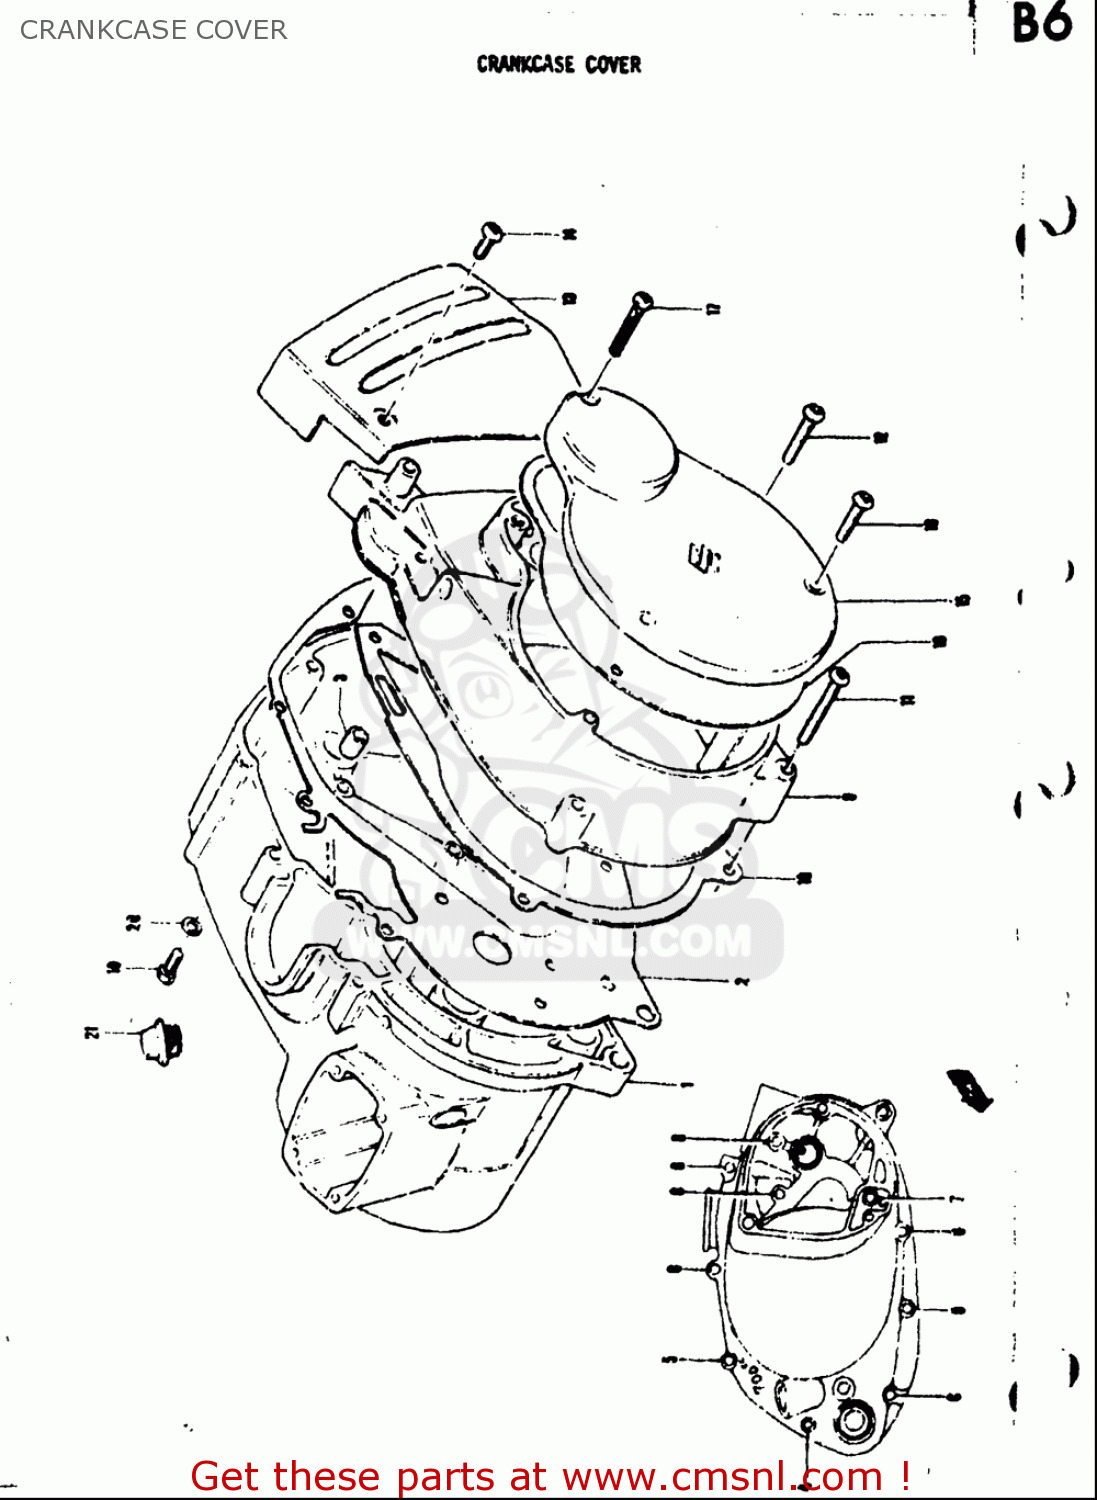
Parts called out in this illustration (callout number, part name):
2	GASKET,CLUTCH COVER (NAS)
3	PIN
4	SCREW
5	SCREW
6	SCREW
7	SCREW
8	SCREW
10	GASKET,MAGNETO COVER (NAS)
11	SCREW
12	SCREW
16	GASKET (MCA)
17	SCREW
18	SCREW
19	SCREW(6X10)
20	GASKET(6.2X11X1) (NAS)
21	PLUG SET
